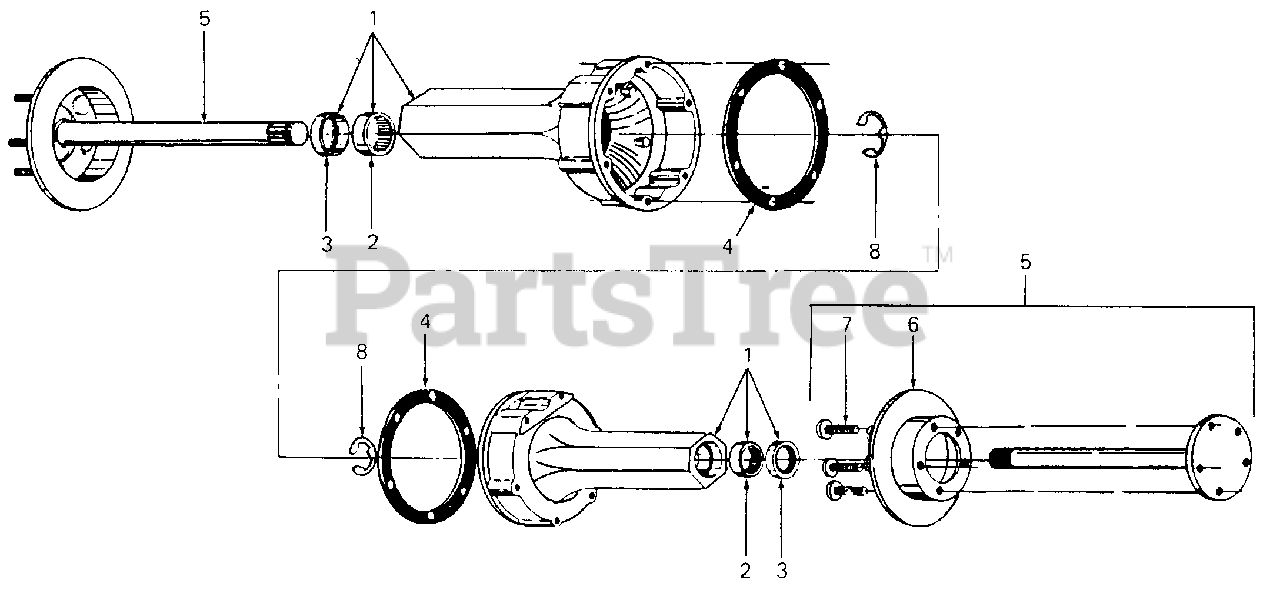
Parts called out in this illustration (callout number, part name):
1	Carrier Assy, Rear Axle
2	Bearing, Needle
3	Seal, Oil
4	Gasket, Carrier
5	Axle Assy, Rear
6	Disc, Brake
7	Bolt, Lug
8	Retainer, E-Ring
